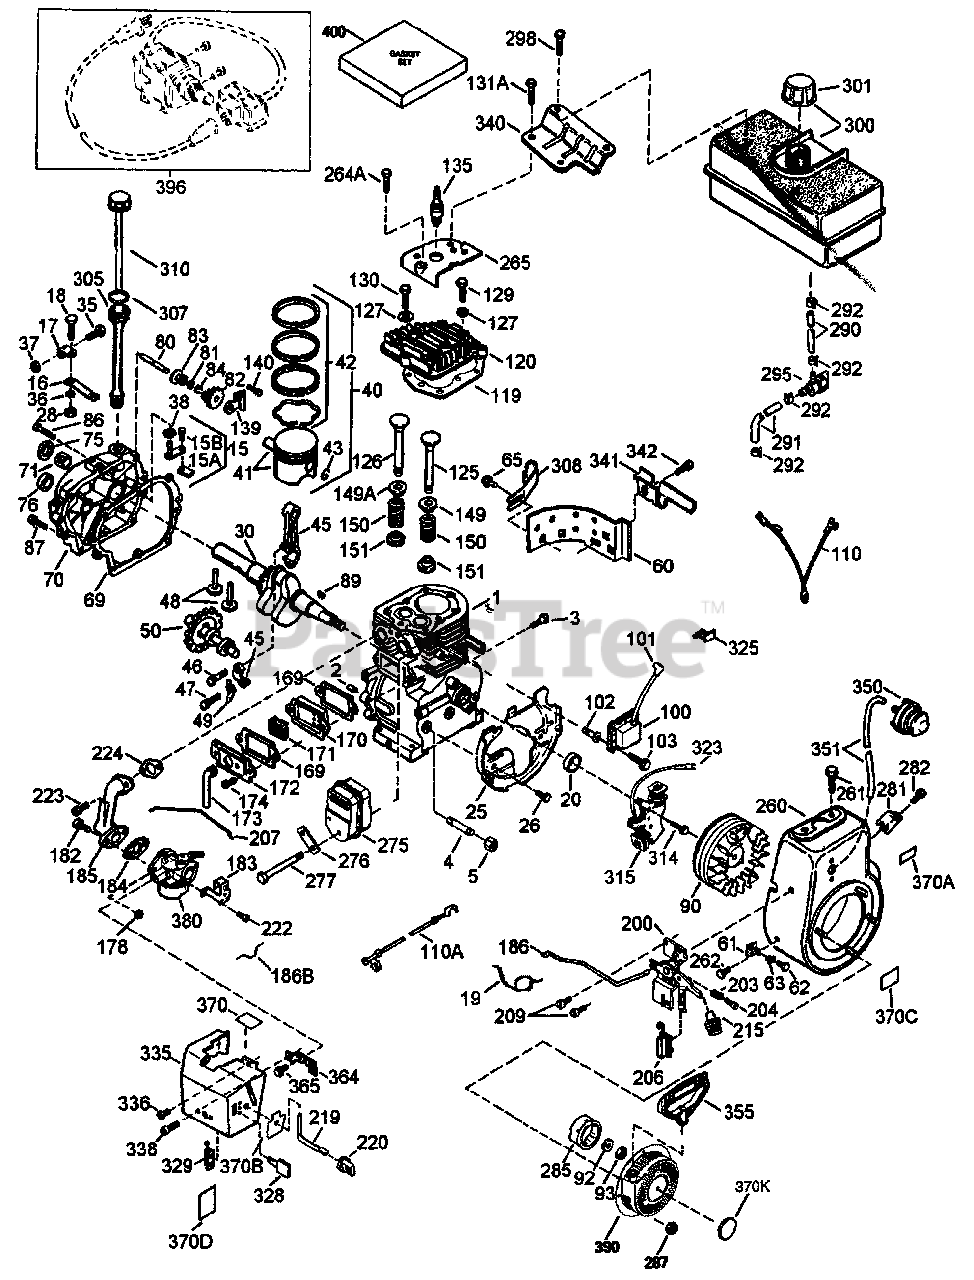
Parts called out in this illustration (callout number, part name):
2	Dowel Pin
3	Screw, 1/4-20 x 1/2"
4	Oil Drain Extension
5	Extension Cap
15	Governor Rod
15A	Governor Yoke
15B	Screw, 6-40 x 5/16"
16	Governor Lever
17	Governor Lever Clamp
18	Screw, 8-32 x 5/16"
19	Speed Control Spring
25	Blower Housing Baffle
26	Screw, 1/4-20 x 5/8"
28	Lock Nut, 8-32
30	Crankshaft
35	Screw, 10-32 x 3/4
36	Lock Washer
37	Lock Nut, 10-32
38	Retaining Ring
40	Piston, Pin, Ring Set (Std)
41	Piston & Pin Assy (Std)
42	Ring Set (Std)
43	Piston Pin Retaining Ring
45	Connecting Rod Assy
46	Connecting Rod Bolt
47	Connecting Rod Bolt
48	Valve Lifter
49	Oil Dipper
50	Camshaft (MCR)
60	Blower Housing Extension
61	Grommet Mounting Bracket
62	Screw, 8-32 x 3/8"
65	Screw & Lockwasher
69	Cylinder Cover Gasket
70	Cylinder Cover
71	Crankshaft Bushing
76	Camshaft Seal
80	Governor Shaft
82	Governor Gear Assy
83	Governor Spool
84	Retaining Ring
86	Screw, 1/4-20 x 1-3/16"
87	Screw, 1/4-20 x 1-11/16"
89	Flywheel Key
90	Flywheel
92	Belleville Washer
93	Flywheel Nut
100	Solid State Ignition
101	Spark Plug Cover
102	Solid State Mounting Stud
103	Screw, Torx T-15, 10-24 x 15/16"
110	Ground Wire
110A	Ground Wire
119	Gasket Cylinder Head
120	Cylinder Head
125	Exhaust Valve (Std)
126	Intake Valve (Std)
129	Screw, 5/16-18 x 1-3/4"
130	Screw, 5/16-18 x 1-1/2"
131A	Screw, 5/16-18 x 5/8"
135	Resistor Spark Plug
139	Governor Gear Bracket
140	Screw, 10-24 x 1/2"
149	Valve Spring Cap
149A	Valve Spring Cap
150	Valve Spring
151	Valve Spring Keeper
169	Valve Cover Gasket
170	Breather Body
171	Breather Element
172	Valve Cover
173	Breather Tube
174	Screw, 10-24 x 1/2"
178	Nut & Lock Washer 1/4-28
182	Screw, 1/4-28 x 1"
183	Choke Bracket
184	Carburetor to Intake Pipe Gasket
185	Intake Pipe
186	Governor Link
186B	Choke Spring
200	Control Bracket
203	Compression Spring
204	Screw, 5-40 x 7/16"
207	Throttle Link
209	Screw, 10-32 x 1/2"
215	Control Knob
219	Choke Rod
220	Choke Knob
222	Screw, 10-32 x 1/2"
223	Screw, Torx T-30, 5/16-18 x 1-1/8"
224	Intake Pipe Gasket
260	Blower Housing
261	Screw, 5/16-18 x 3/4"
262	Screw, Torx T-40, 5/16-24 x 21/32"
264A	Screw, 1/4-20 x 5/8"
265	Cylinder Head Cover
276	Locking Plate
277	Screw, 5/16-18 x 4-3/16"
281	Starter Bubble Cover
282	Screw, 8-32 x 3/8"
285	Starter Cup
287	Nut & Lock Washer, 1/4-28
290	Fuel Line
291	Fuel Line
292	Fuel Line Clamp
295	Fuel Shut-Off Valve
298	Screw, 1/4-15 x 7/8"
301	Fuel Cap
305	Oil Fill Tube
308	Fill Tube Clip
314	Screw, 1/4-20 x 3/4"
315	Alternator Coil
325	Wire Clip
328	Ignition Keys
335	Carburetor Cover
336	Screw, 10-32 x 1/2"
338	Screw, 10-32 x 1/2"
340	Fuel Tank Bracket
341	Fuel Tank Bracket
342	Screw, 1/4-20 x 5/8"
350	Primer Assy
351	Primer Line
355	Starter Handle
364	Carburetor Cover Bracket
365	Screw, 8-32 x 27/64"
370	Warning decal
370A	Primer Decal
370B	Lubrication Decal
370C	Identification Decal
370D	Instruction Decal
370K	Starter Decal
390	Starter Recoil
396	Electric Starter Motor
400	Gasket Set
